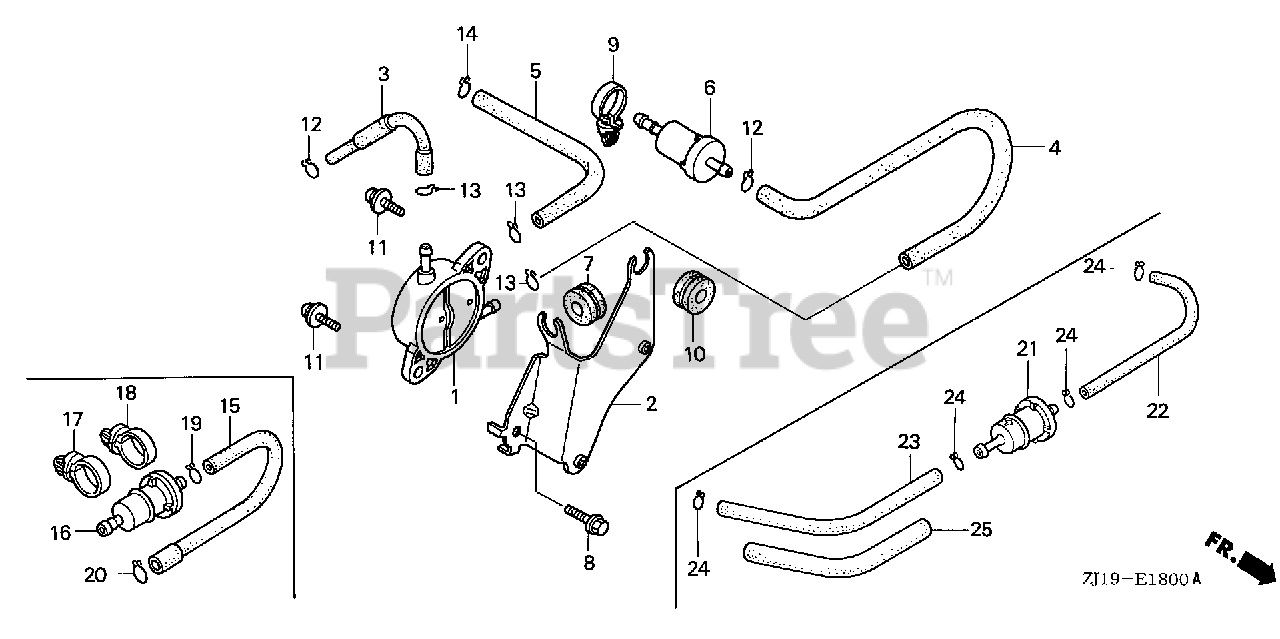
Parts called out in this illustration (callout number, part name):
1	PUMP ASSY., FUEL
2	STAY, FUEL PUMP
3	TUBE COMP. A, FUEL
4	TUBE B, FUEL
5	TUBE, DIAPHRAGM
6	FILTER COMP., FUEL
7	GROMMET, RESERVE TANK
8	BOLT, FLANGE (6X14)
9	CLIP, WIRE HARNESS
10	GROMMET, PUMP STAY
11	SCREW-WASHER (6X16)
12	CLIP, TUBE (B8)
13	CLIP, TUBE (B10)
14	CLIP, TUBE (C9)
